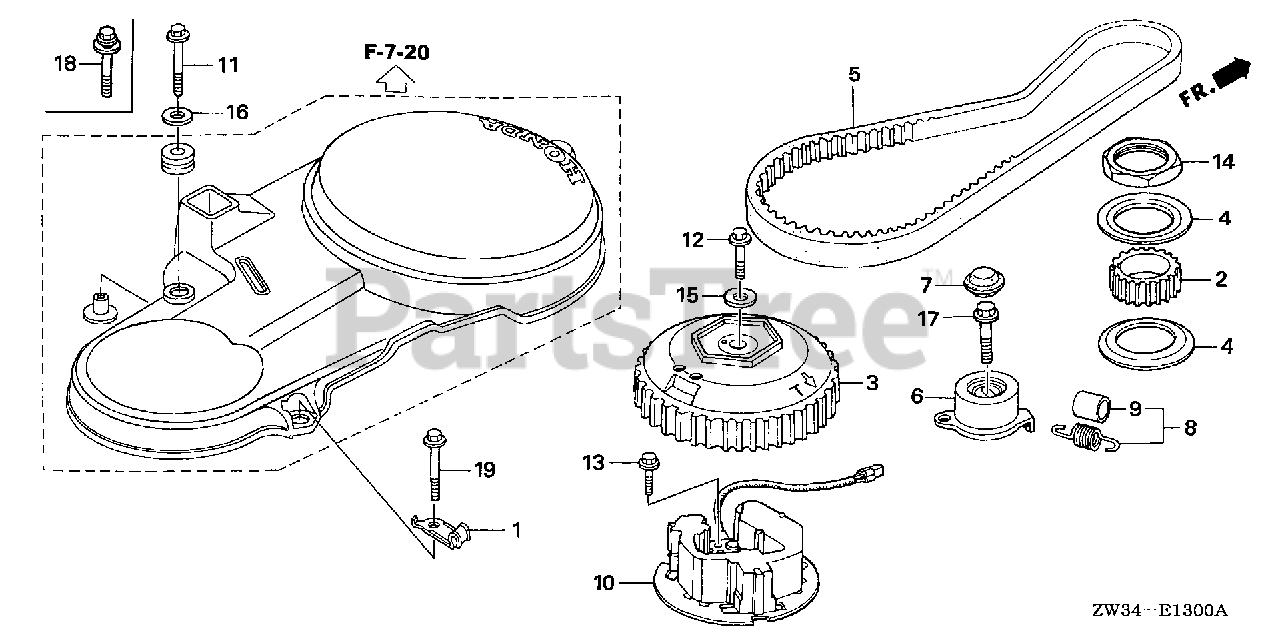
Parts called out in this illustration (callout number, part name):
1	CLAMP, TUBE
2	PULLEY, TIMING
3	PULLEY, CAMSHAFT
4	PLATE, TIMING BELT GUIDE
5	BELT, TIMING
6	TENSIONER, TIMING BELT
7	CAP, TIMING BELT TENSIONER
8	SPRING, TIMING BELT ADJUSTING
9	BOOT, SPRING
10	COIL ASSY., PULSER
11	BOLT, FLANGE (6X25)
12	BOLT, FLANGE (10X32)
13	BOLT, FLANGE (6X12)
14	NUT, LOCK (48MM)
15	WASHER (10X28X5)
16	WASHER, PLAIN (6MM)
17	BOLT, FLANGE (10X38)
19	BOLT, FLANGE (6X25)
